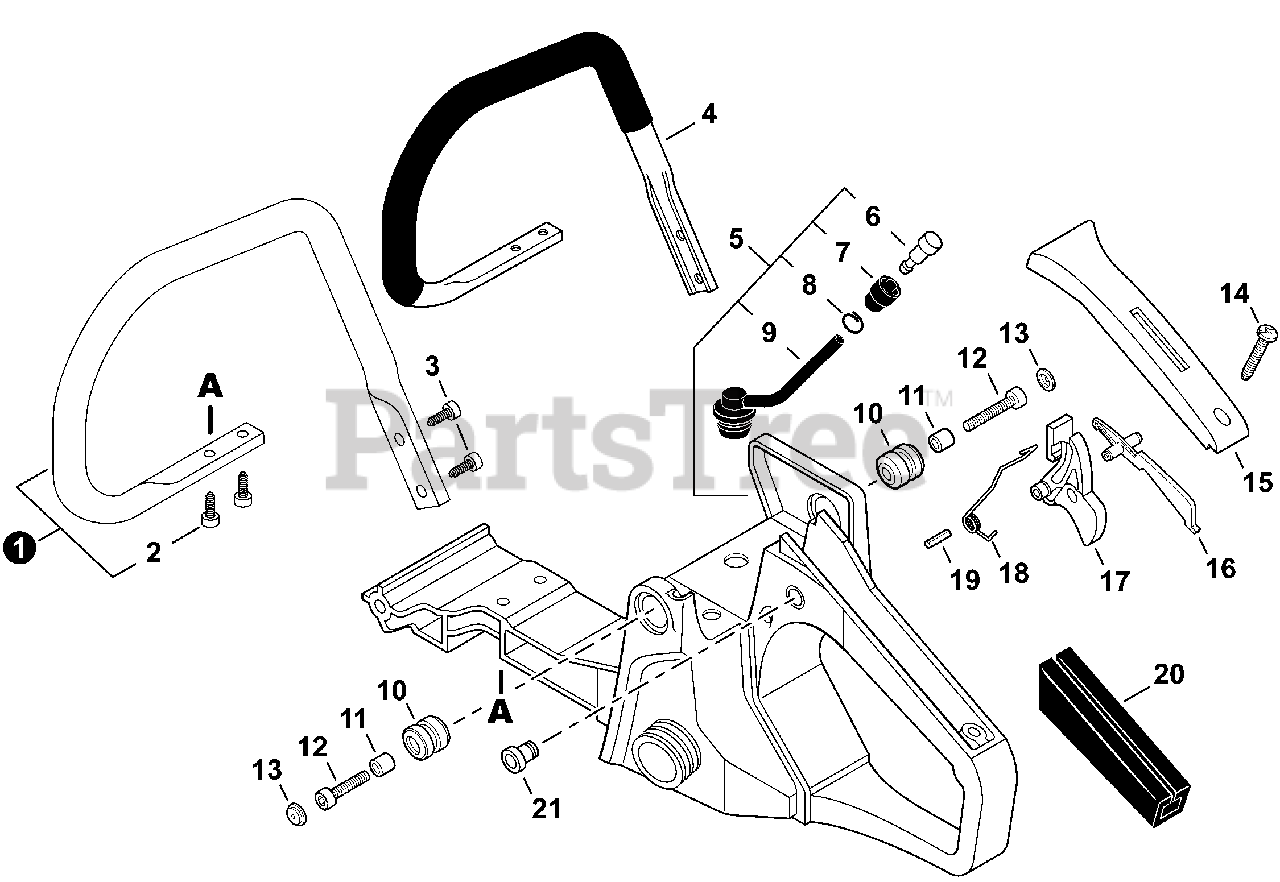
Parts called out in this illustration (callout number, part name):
1	HANDLE SET, FRONT - NYLON
2	SCREW TAPPING 5×20
3	SCREW TAPPING 5×20
4	HANDLE, FRONT - ALUMINUM
5	HANDLE ASSY, REAR
6	VENT ASSY
7	HOLDER, VENT
8	CLIP 6.5 MM
9	PIPE, VENT 3×6×65
10	CUSHION 4
11	COLLAR 4.2×7×9.5
12	BOLT, HEX 4×20
13	CAP, CUSHION
14	SCREW 4×14
15	COVER, HANDLE
16	LOCKOUT, THROTTLE
17	TRIGGER, THROTTLE
18	SPRING, TORSION
19	PIN, SPRING 4×30
20	GRIP, HANDLE
